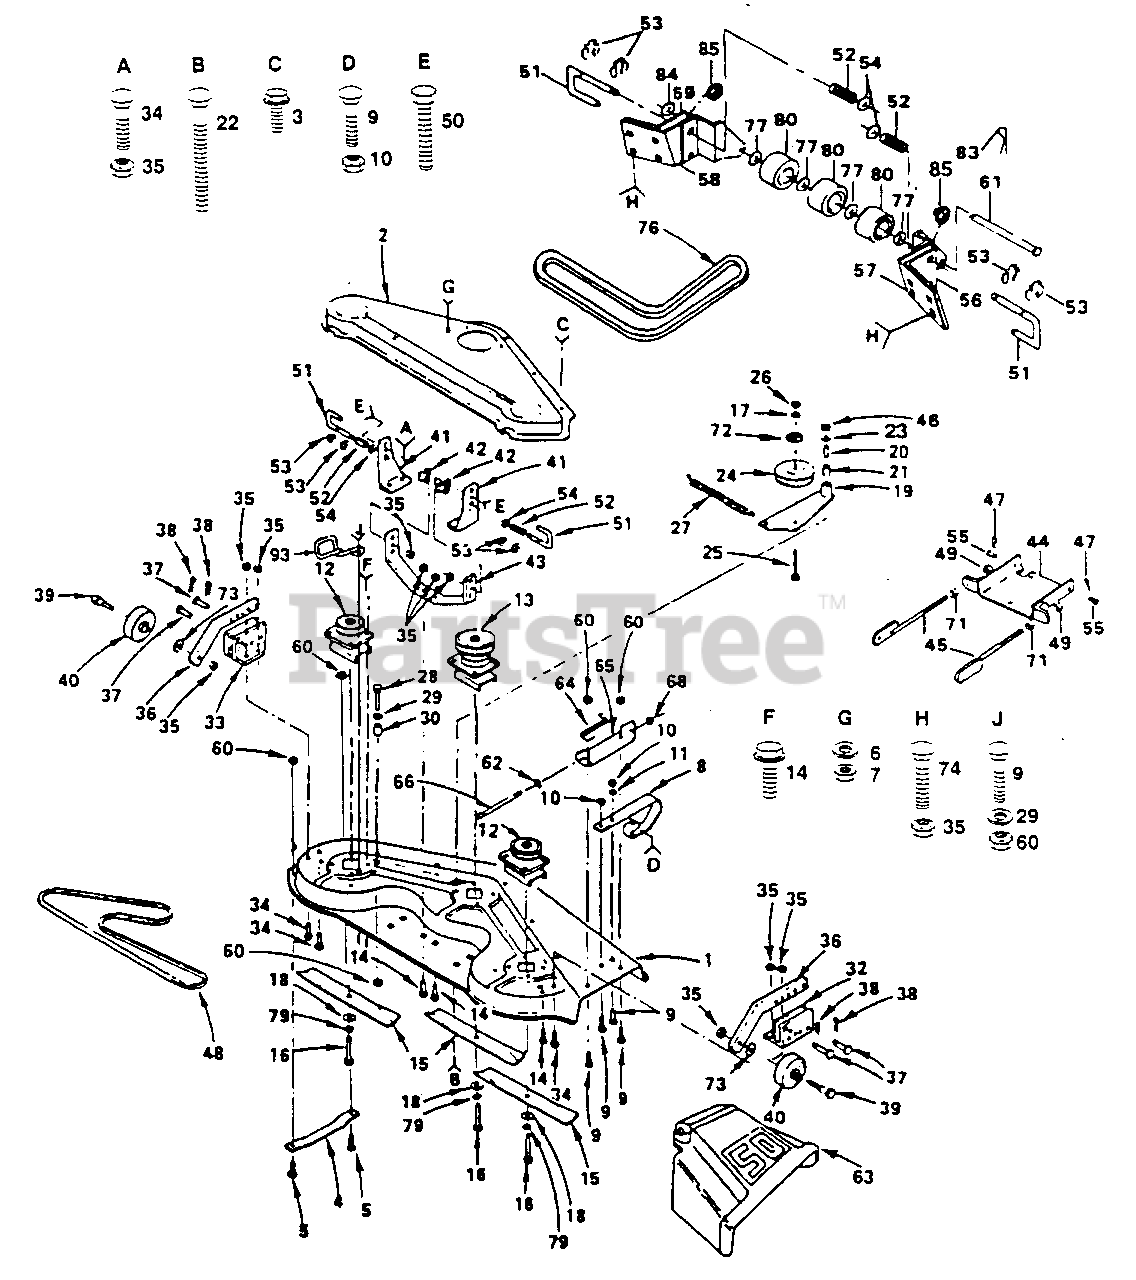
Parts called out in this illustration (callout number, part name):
1	Housing, Mower (AYP part number)
2	Cover, Drive, Deck (AYP part number)
3	Screw, Hex Washer Thd. Roll 5/16-18 x 1/2 (AYP part number)
4	Runner, L.H. (AYP part number)
5	Bolt, Carraige 5/16-18 x 5/8 (AYP part number)
6	Washer, Lock 5/16 (AYP part number)
7	Nut, Hex 5/16-18 (AYP part number)
8	Runner, R.H. (AYP part number)
9	Bolt, Carriage 5/16-18 x 3/4
10	Locknut 5/16-18 (AYP part number)
11	Washer 11/32 x 11/16 x 16 Ga. (AYP part number)
12	Mandrel, Secondarv (AYP part number)
13	Mandrel, Primary (AYP part number)
14	Screw, Hex Washer, Thd. Roll 3/8-16 x 3/4 (AYP part number)
16	Bolt, Hex 3/8-24 x 1-1/2 Gr. 5 (AYP part number)
17	Washer, Lock 3/8 (AYP part number)
18	Washer 13/32 x 1-1/4 x 12 Ga. (AYP part number)
19	Arm Assembly, Idler (AYP part number)
20	Liner, Bearing (AYP part number)
21	Bearing (AYP part number)
22	Bolt, Carriage 5/16-18 x 2-3/4 (AYP part number)
23	Washer 11/32 x 1-1/8 x 16 Ga. (AYP part number)
24	Pulley, Idler (AYP part number)
25	Bolt, Hex 3/8-16 x 1-1/2 (AYP part number)
26	Nut, Hex 3/8-16 (AYP part number)
27	Spring (AYP part number)
28	Bolt, Hex 5/16-18 x 1-1/4 Gr. 5 (AYP part number)
29	Washer 11/32 x 3/4 x 16 Ga. (AYP part number)
30	Spacer, Split (AYP part number)
32	Bracket, Ga. Wheel, R.H. (AYP part number)
33	Bracket, Ga. Wheel, L. H. (AYP part number)
34	Bolt, Carriage 3/8-16 x 3/4 (AYP part number)
35	Nut, Crownlock 3/8-16
36	Bar, Ga. Wheel (AYP part number)
37	Pin, Clevis (AYP part number)
38	Retainer, Spring (AYP part number)
39	Bolt, Shoulder (AYP part number)
40	Wheel, Gauge (AYP part number)
41	Bracket, Suspension (AYP part number)
42	Spacer (AYP part number)
43	Brace, Suspension (AYP part number)
44	Plate Assembly, Mower Suspension (AYP part number)
45	Bracket, Suspension (AYP part number)
46	Nut, Hex 5/16-18 (AYP part number)
47	Retainer, Spring (AYP part number)
48	V-Belt (AYP part number)
49	Nut, Crownlock 1/2-13 (AYP part number)
50	Bolt, Hex 3/8-16 x 1-3/8 (AYP part number)
51	Pin, Release (AYP part number)
52	Spring (AYP part number)
53	Ring, Klip (AYP part number)
54	Washer 17/32 x 1 x 12 Ga. (AYP part number)
55	Pin, Clevis (AYP part number)
56	Bracket, Outer, R.H. (AYP part number)
57	Bracket, Inner, R.H. (AYP part number)
58	Bracket, Inner, L.H.
59	Bracket, Outer, L.H. (AYP part number)
60	Locknut 5/16-18
61	Pin, Pivot (AYP part number)
62	Washer 11/32 x 5/8 x 16 Ga. (AYP part number)
63	Shield, Deflector (AYP part number)
64	Spring, Deflector (AYP part number)
65	Bracket, Deflector (AYP part number)
66	Rod, Hinge (AYP part number)
68	Nut, Push (AYP part number)
71	Nut, Hex 1/2-13 (AYP part number)
72	Washer 13/32 x 1 x 14 Ga. (AYP part number)
73	Washer 17/32 x 15/16 x 12 Ga. (AYP part number)
74	Bolt, Carriage 3/8-16 x 1 (AYP part number)
76	V-Belt (AYP part number)
77	Washer 15/32 x 1 x 10 Ga. (AYP part number)
79	Washer, Lock 3/8 (AYP part number)
80	Roller, Nose (AYP part number)
83	Hairpin, Cotter (AYP part number)
84	Washer 15/30 x 1 x 16 Ga. (AYP part number)
85	Spacer (AYP part number)
93	Keeper, LH. (AYP part number)
